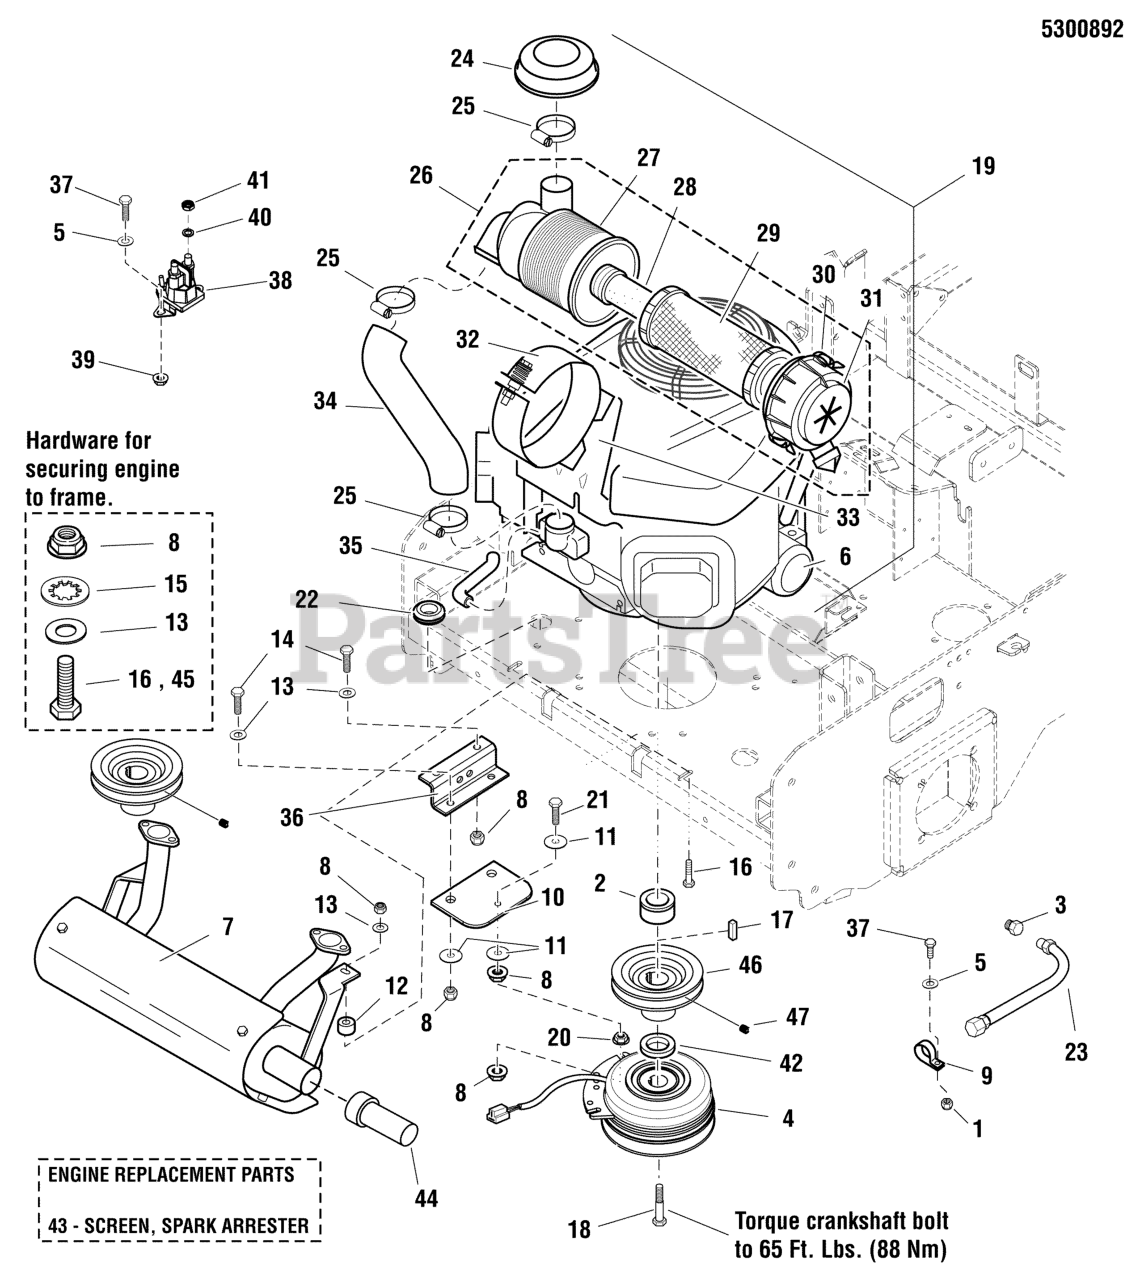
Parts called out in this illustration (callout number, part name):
1	NUT, 1/4-20 HEX NYLOCK FLANGE
2	SPACER, 1.13 X 1.75 X 1.03
3	ADAPTER, OIL DRAIN
4	* CLUTCH, 5218-134, WARNER
5	WASHER, 1/4 SAE
6	OIL FILTER (49065-2078) (SV)
6	OIL FILTER
7	MUFFLER, 21HP-25HP KAWASAKI ENGINES
7	MUFFLER, (16-20HP), KAWASAKI S50X
7	MUFFLER, KAWI, HORIZONTAL, 5" CAN
8	NUT, 5/16-18 HEX NYLOCK FLANGE
9	CLAMP, VINYL INSULATED
10	CLUTCH ANCHOR PAD
11	WASHER, .34 X 1.25 X 10 GA
12	SPACER, .39 X 1.00 X .80
13	WASHER, 5/16" SAE
14	BOLT, 5/16-18 X 1 GD5 YZ
15	WASHER, 5/16" INT. TOOTH LOCK
16	BOLT, 5/16-18 X 1-3/4 GD5 YZ
17	KEY, 1/4 SQ X 1
18	BOLT, CRANKSHAFT, 7/16 X 2-1/2
20	NUT, 5/16-18 HEX SERRATED FLANGE (SMALL)
21	BOLT, 5/16-18 X 2-1/4 TFL, GD5 YZ
22	GROMMET, 7/8
23	HOSE, OIL DRAIN
24	RAIN COVER (SV)
25	CLAMP (SV)
26	AIR FILTER ASSEMBLY (SV)
27	CASE, AIR FILTER (SV)
28	AIR FILTER, SECONDARY (SV)
29	AIR FILTER, PRIMARY (SV)
30	CLAMP, CAP (SV)
31	CAP, FILTER CASE (SV)
32	CASE, BRACKET, COMPLETE (SV)
33	BRACKET PLATE (SV)
34	AIR INLET TUBE (SV)
35	BREATHER TUBE (SV)
36	ANCHOR, CLUTCH - BLK
37	BOLT, 1/4-20 X 3/4 GD5 YZ
38	SOLENOID-4 POLE 12 VOLT DC (TROMBETTA)
39	NUT, 1/4-20 HEX SERR. FLANGE
40	WASHER, 5/16 LIGHT LOCK (SV)
41	NUT, 5/16-24 JAM (SV)
42	SPACER, 1.13 X 1.75 X .32
42	SPACER, 1.13 X 1.75 X .62
42	SPACER, 1.13 X 1.75 X .50
43	SCREEN, SPARK ARRESTER
44	EXTENSION, TAILPIPE, 3" - BLACK
45	BOLT,HEX FLG,SER GD5 3/8-16X1-1/4PACH CZ
46	PULLEY, 5.15 OD X 1-1/8 BORE B-SECT
47	SET SCREW, 5/16-18 X 3/8, KNURL, W/PATCH
